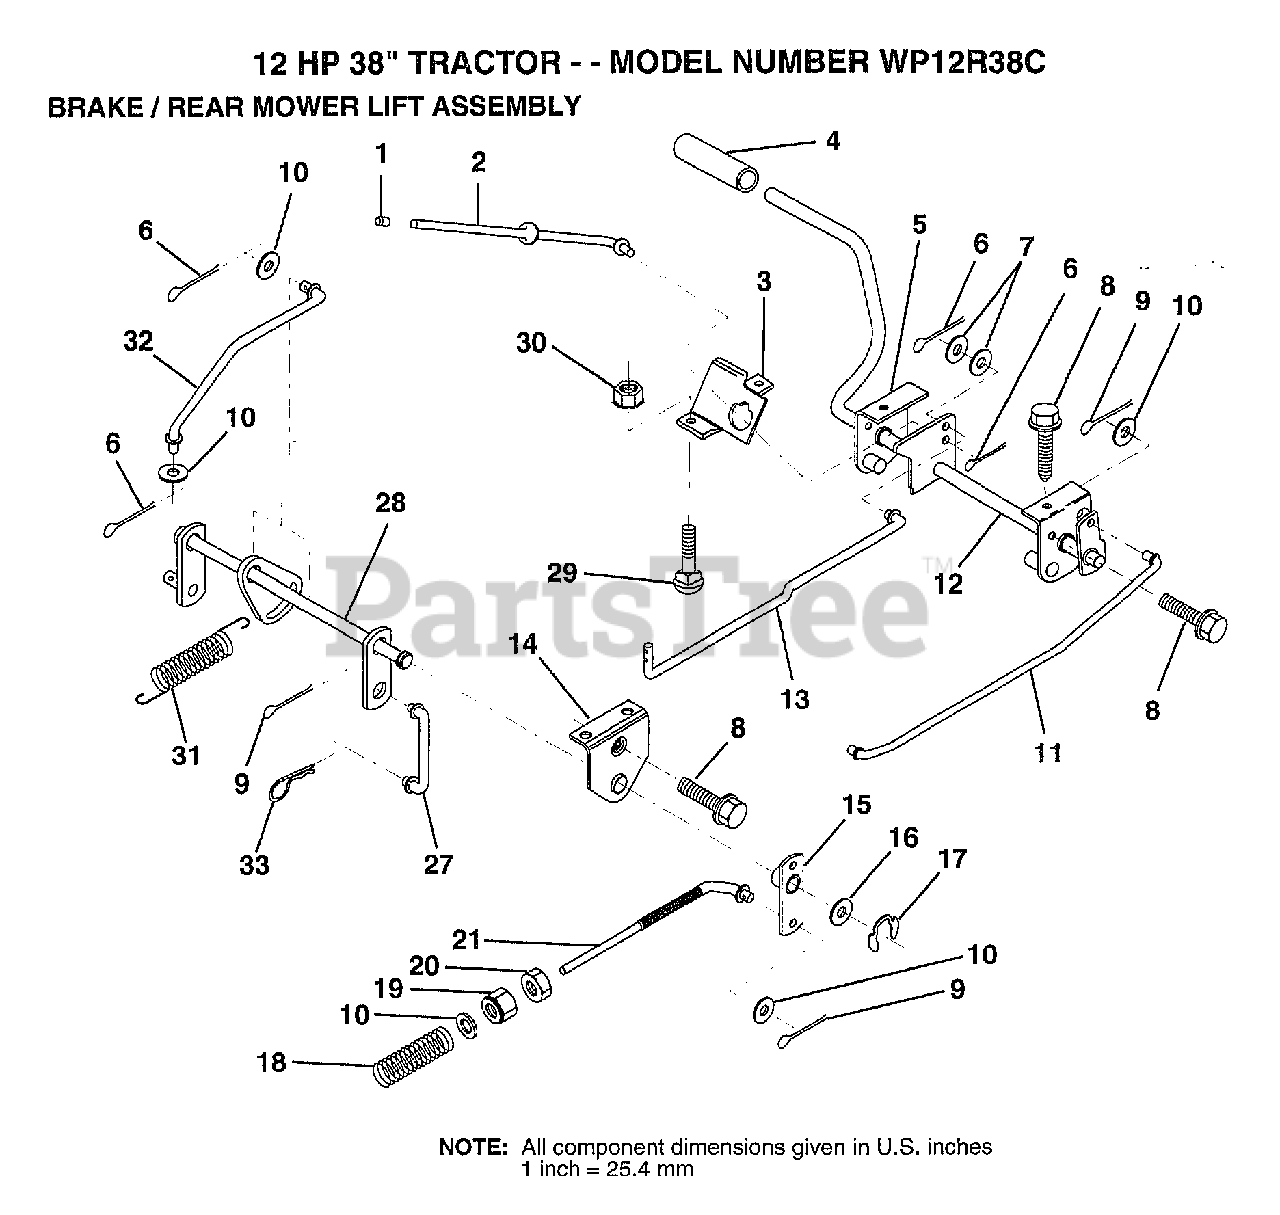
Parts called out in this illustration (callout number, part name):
1	PLUNGER CAP T
2	"ROD,PARK BRAKE"
3	"BRKT,PARK BRAKE"
4	PEDAL COVER T
5	BRK ASM CLUT LH
7	WASHER
8	SCREW LT
9	COTTER PIN
10	WASHER
11	"ROD,FRT BRAKE"
12	PEDAL ASM CLU/BRK
13	"ROD,CLUTCH"
14	"BRKT,LIFT SHAFT"
15	PVT BRAKE ARM ASM
16	WASHER T
17	KLIP RING
18	SPRING ROD LT
19	NUT
20	NUT
27	LINK LIFT REAR LR
28	LIFT.ASM.REAR.LR
31	COUNTER SPRING
32	LINK LIFT LEVER
